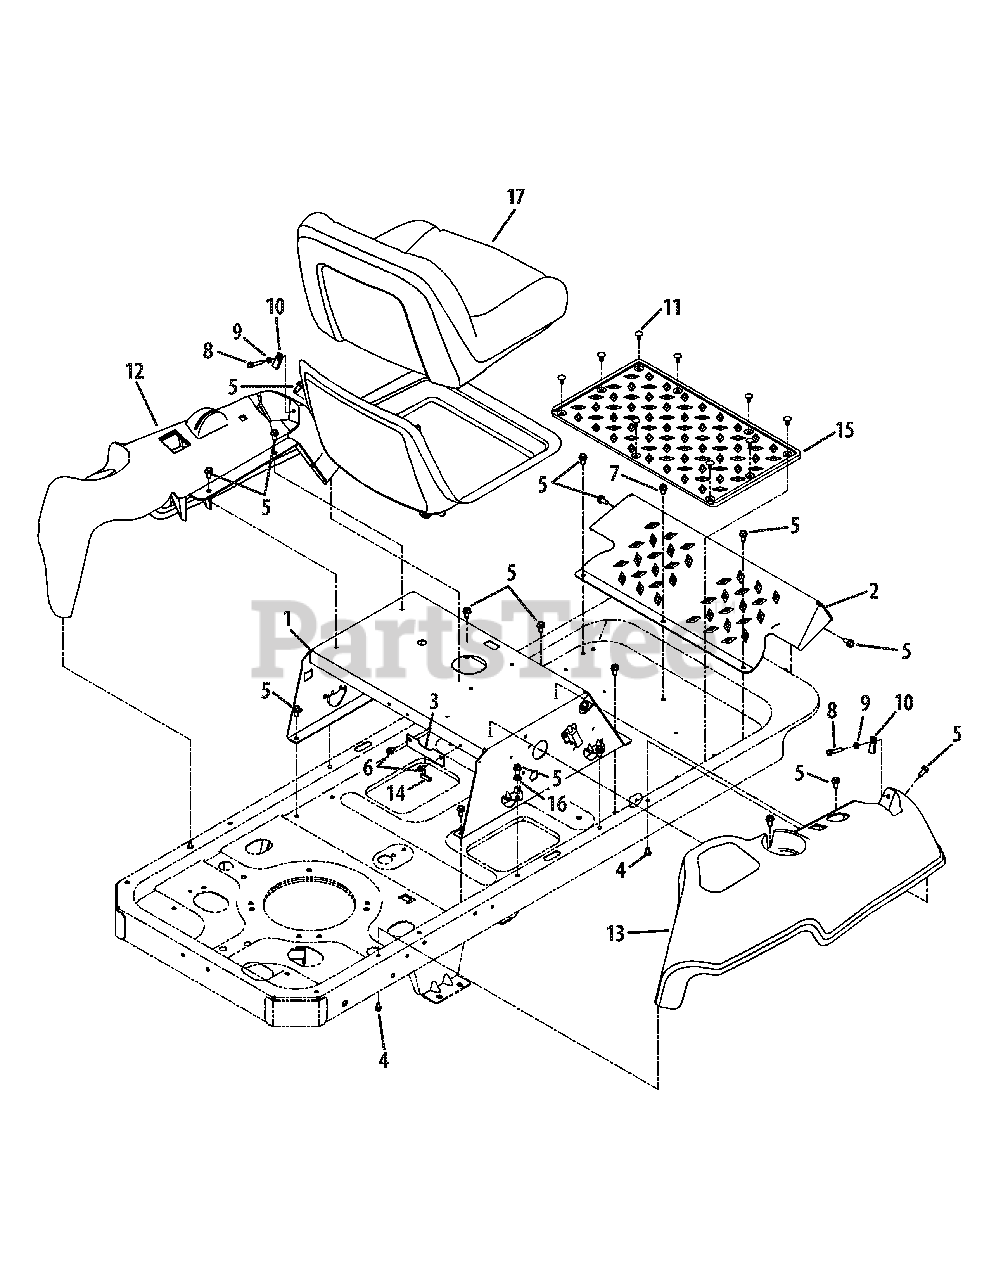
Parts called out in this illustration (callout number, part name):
1	Seat Frame Assembly (NLA) - Black Jack
1	Seat Frame Assembly - Black Jack
1	Seat Frame Assembly (NLA) - Green
1	Seat Frame Assembly - Green
2	Foot Rest Bracket - Black Jack
2	Foot Rest Bracket - Green
3	Batter Hold-Down Bracket
4	Hex Washer Screw, 1/4-15 x .50
5	Hex Washer Screw, 5/16-18 x .750
6	Hex Washer Screw, 1/4-20 x .500
7	Hex Washer Screw, 5/16-18 x .625
8	Hex Washer Screw, 1/4-20 x 1.500
9	Jam Nut, 1/4-20
10	U-Type Nut, 1/4-20
11	Ratchet Clip
12	LH Console (Black)
12	LH Console (Oyster Gray)
13	RH Console (Black)
13	RH Console (Oyster Gray)
14	Trim Strip
15	Foot Pad
16	Lock Washer, 3/8
17	High-Back Seat
